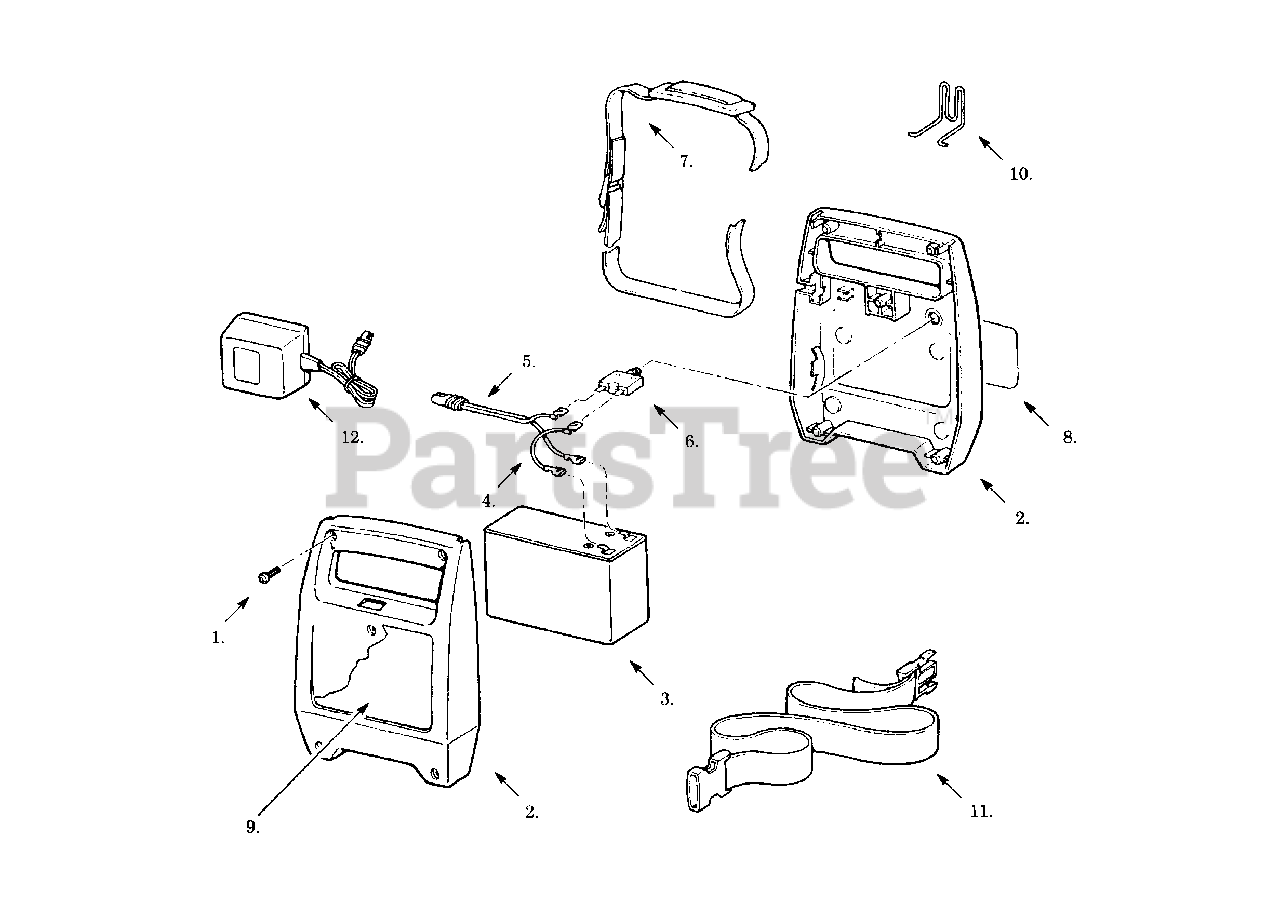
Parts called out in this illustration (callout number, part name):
2	Housing Set
4	Wire Assembly
5	Plug Assembly
6	Circuit Breaker
7	Shoulder Strap
10	Belt Hook
11	Waist Belt
